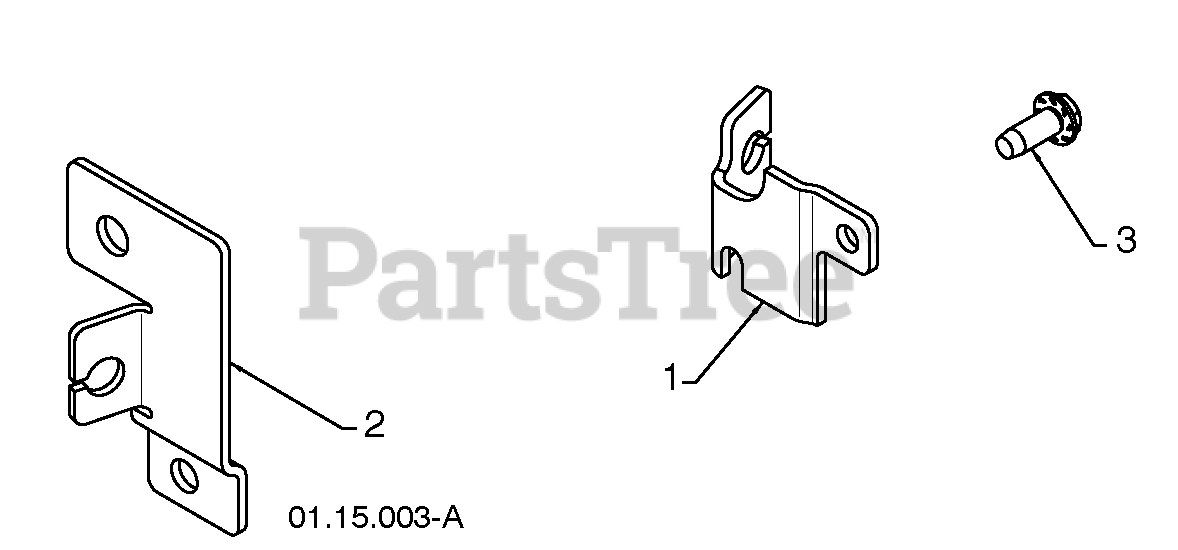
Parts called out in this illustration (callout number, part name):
1	CABLE BRACKET LH
2	CABLE BRACKET RH
3	SCREW 1/4-20 X .625
